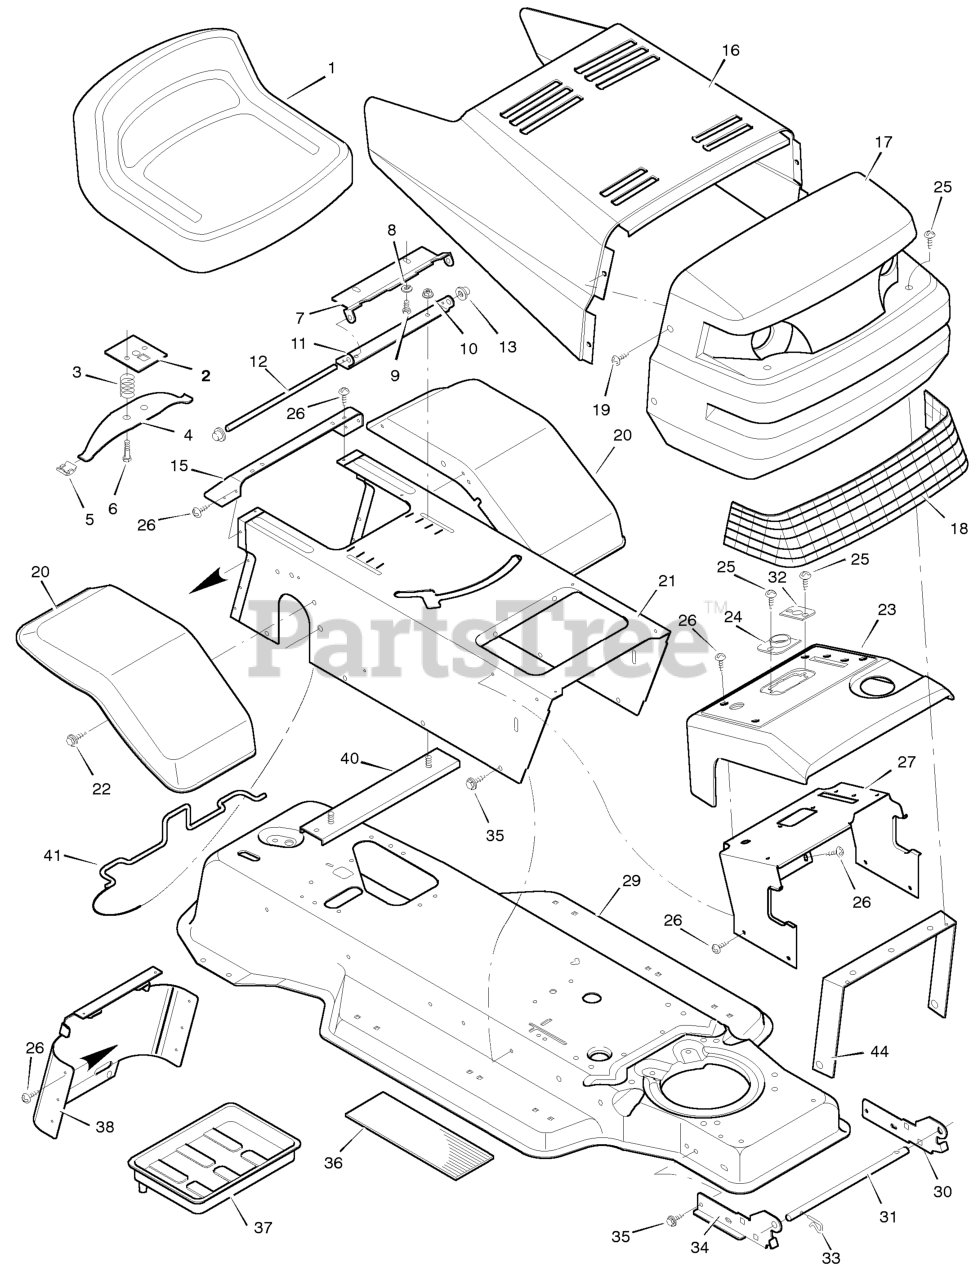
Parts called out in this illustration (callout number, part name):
2	Plate Assembly, Switch
3	Spring, Compression
4	Spring, Seat
5	Glide, Spring
6	Bolt, Shoulder
7	Support, Seat
8	Lockwasher
9	Bolt, Hex
10	Locknut, Flange
11	Bracket, Pivot
12	Rod, Pivot
13	Cap, Push On
15	Fender, Apron
17	Grille Assembly
21	Console Assembly
23	Dash Panel
24	Bearing, Steering
26	Screw
27	Support, Dash
29	Frame Assembly
30	Bracket, Left Grille
31	Rod, Pivot
32	Bearing
33	Pin, Hair
34	Bracket, Right Grille
37	Tray, Battery
38	Cap, Console
39	Bolt
40	Channel Assembly
41	Clamp, Battery
44	Brace, Grille
